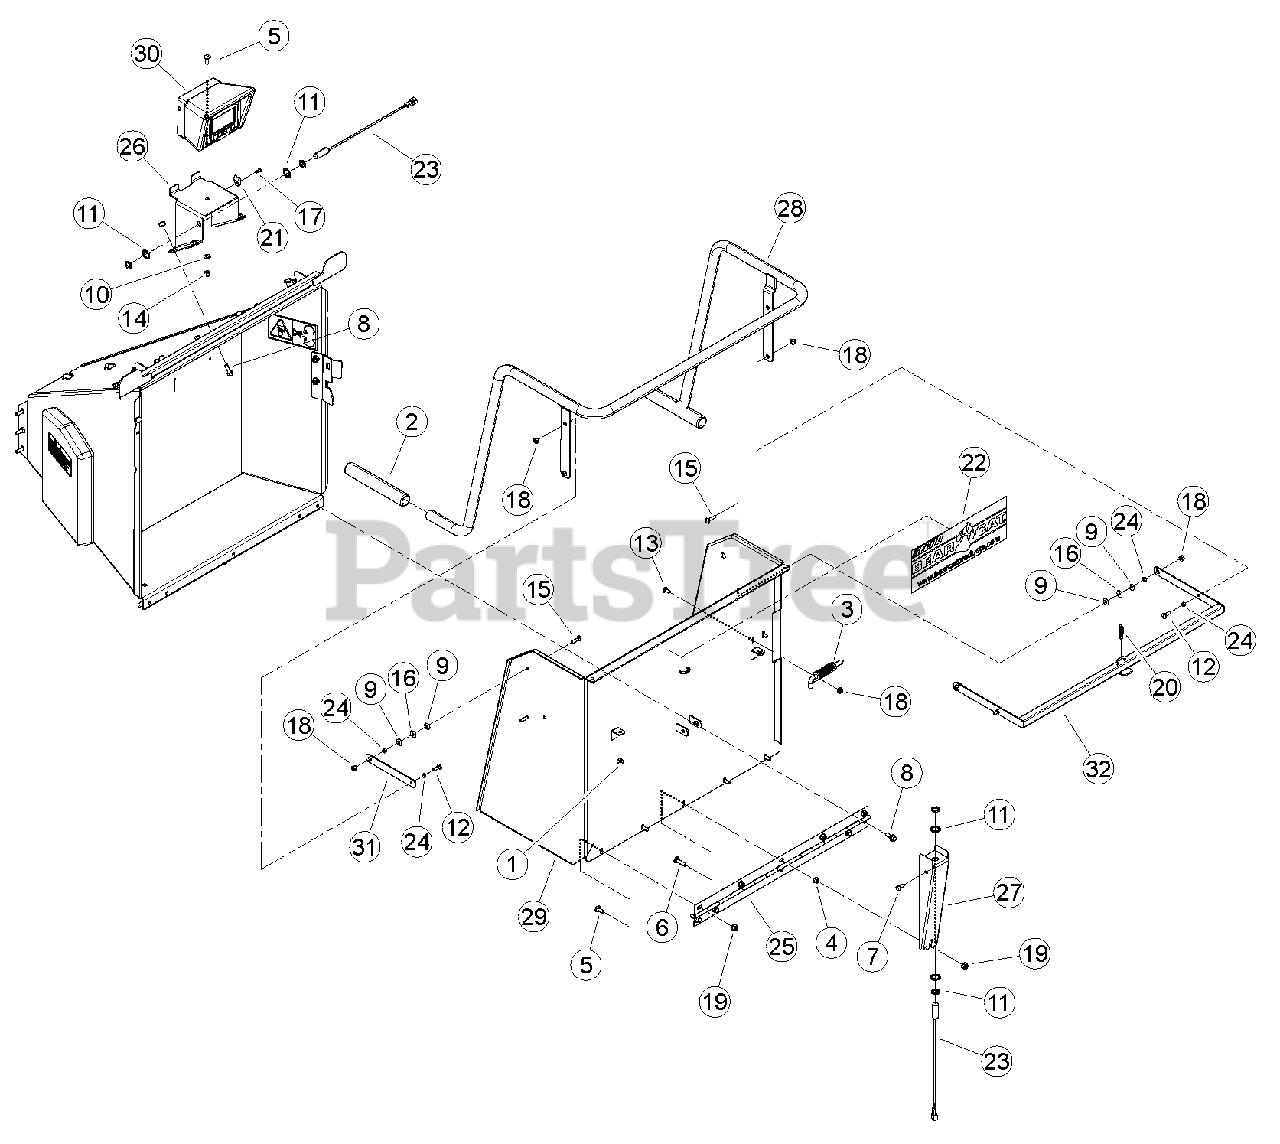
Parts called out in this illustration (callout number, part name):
1	BUMPER, RUBBER
2	GRIP, 1.219 X 10.00
3	LATCH, RH HINGE
4	NUT, 3/8" SERRATED FLANGE NC ZP
5	BOLT, 3/8 X 1" GR5 CRG NC ZP
6	BOLT, 3/8 X 1-1/2" GR5 CRG NC ZP
7	BOLT, 5/16 X 3/4 FLANGE NC
8	BOLT, 3/8 X 1 FLANGE NC
9	WASHER, 5/16" FLAT ZP
10	WASHER, 3/8" SAE FLAT ZP
11	WASHER, 3/4 INTERNAL LOCK
12	BOLT, 5/16 X 1" GR5 CRG ZP
13	BOLT, 5/16 X 3/4 GR5 CRG NC ZP
14	NUT, 3/8" NE NYLOCK ZP
15	BOLT, 5/16 X 1-1/4" GR5 CRG ZP
16	WASHER, 5/16" ID 7/8" OD NYLON FLAT
17	RIVET, AL BLIND 1/4 X 3/4 DOME HEAD
18	NUT, 5/16-18 NYLOCK-FLANGE
19	NUT, 3/8-16 NYLOCK FLANGE
20	SPRING, 1/2 X 2.00 LG ZP
21	CLAMP, CABLE MOUNT
22	DECAL, BEARCAT WEB
23	SENSOR, M18 PROXIMITY (REPLACEMENT PART)
24	SPACER, IDLER PIVOT
25	HINGE, EXTENSION TRAY
26	MOUNT, 5/8/9" DDC
27	MOUNT, 5/8/9" KNEEBAR PROX SENSOR
28	WELDMENT, 8/9" SAFETY KNEEBAR
29	WELDMENT, INFEED TRAY
30	ASSEMBLY, DDC ENCLOSURE
31	LINK, PARALLEL
32	WELDMENT, KNEEBAR PIVOT
